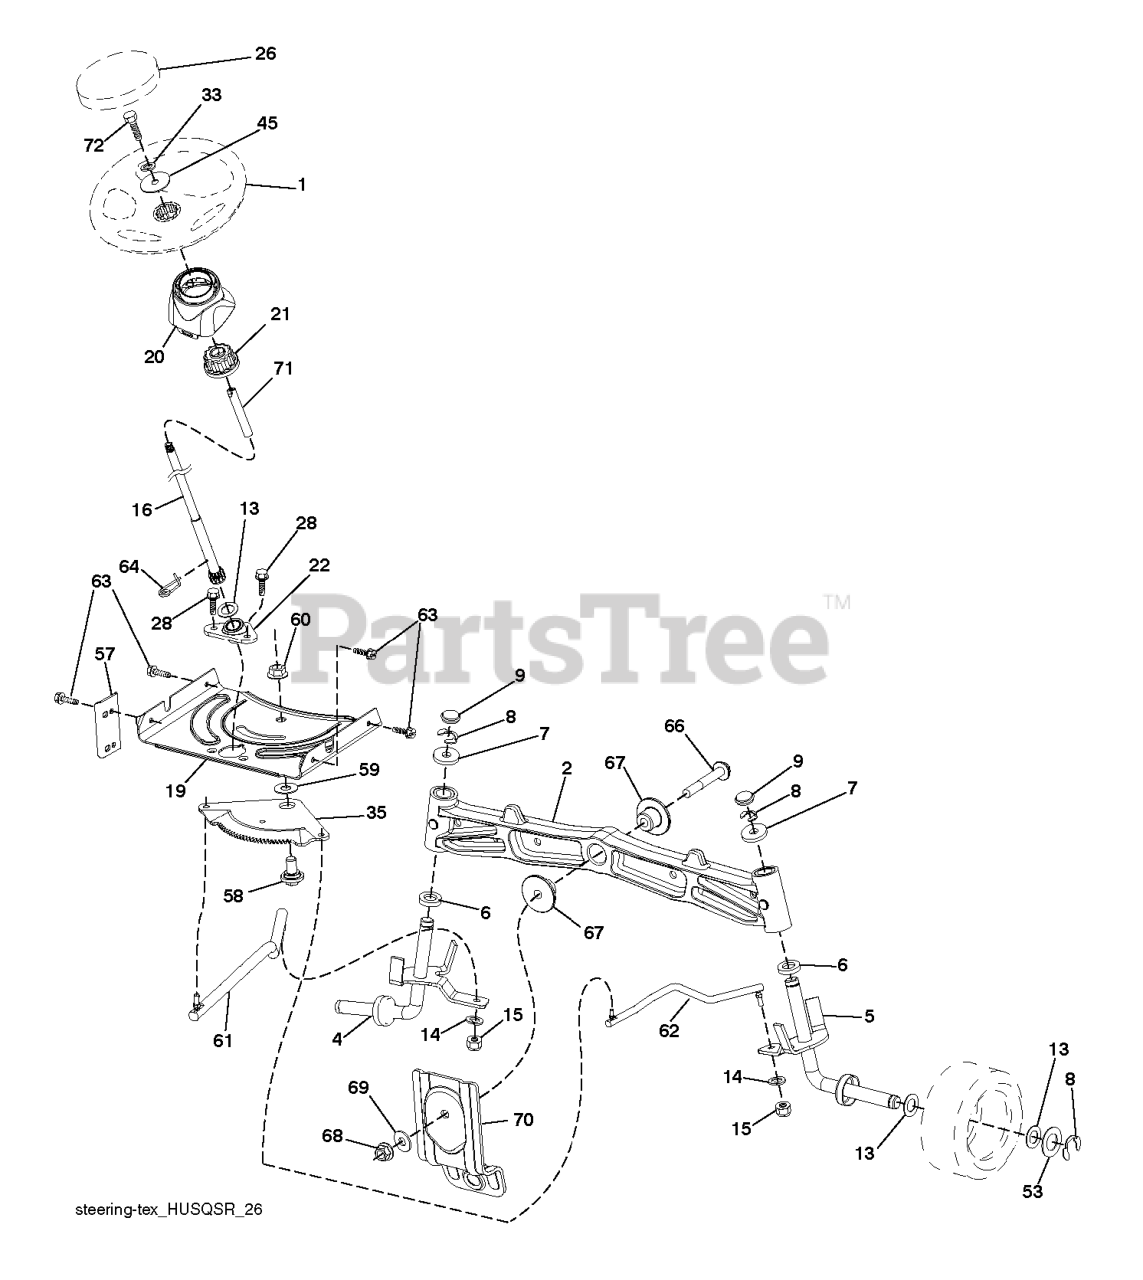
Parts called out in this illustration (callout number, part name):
1	WHEEL.STEER.HUSQ.SR.498.OVMLD
2	AXLE.CAST.IRON
4	SPINDLE.WELDED.LH.15"TEX
5	SPINDLE.WELDED.RH.15"T
6	THRUST WASHER
9	CAP.SPINDLE.BLACK
14	WASHER, LOCK 3/8
15	NUT CROWNLOCK 3/8-24
16	SHAFT.STEER.3/4.PLATED.TEX
19	PLATE.STEER.DDL.NLT/NG
20	STEERING.BOOT.HUSQ.LT
21	ADAPTER, WHEEL STNG..
22	STEERING.SUPT.LOWER.
26	INSERT.CAP.WHL.STRG.HUSQ.PREM
28	SCREW, 3/8-16X3/4
33	WASHER.LOCK.HVY.HLCL.SPR.5/16
35	GEAR.SECTOR.PLATE.DDL.
45	WASHER.11/32
53	WASHER.HARDENED
57	BRACKET.UPSTOP.TEX
58	BOLT.SHOULDER.SECTOR.P
59	WASHER.THURST.SECTOR.S
60	NUT FLANGE LOCK 5/8-11
61	DRAGLINK.LH.BALLSTUD.D
62	DRAGLINK.RH.BALLSTUD.D
63	SCREW
64	RETAINER.CLIP.SPRING.S
66	BOLT HEX FGHD 7/16-14 X 3 SERR
67	BUSHING.PM.FRONT AXLE
68	NUT.LOCK.FLANGE.7/16
69	WASHER.1.5X.505X.118
70	BRKT.DECK.SUSPENSION.F
71	SHAFT.EXTEN.STRG.SPLINE
72	BOLT 5/16-18 X 4 W/PATCH
